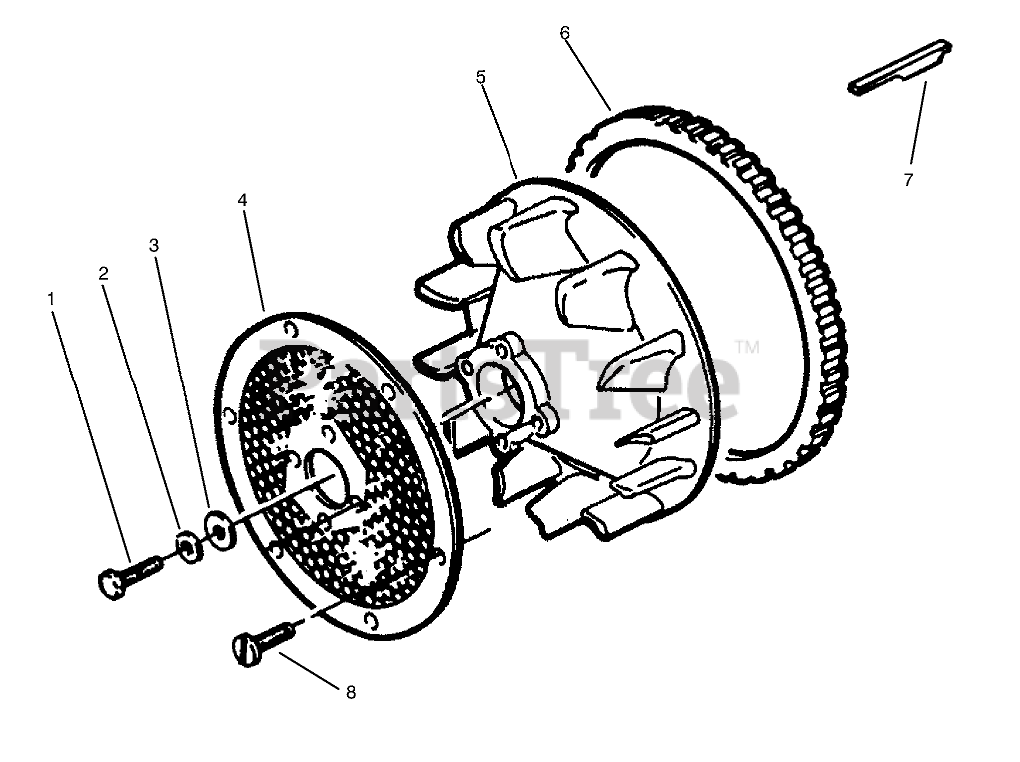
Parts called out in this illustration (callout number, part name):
1	SCREW
2	WASHER-FLAT
3	WASHER-FLAT
4	Screen
5	WHEEL BLOWER
7	KEY-FLYWHEEL
8	LOCK SCREW
